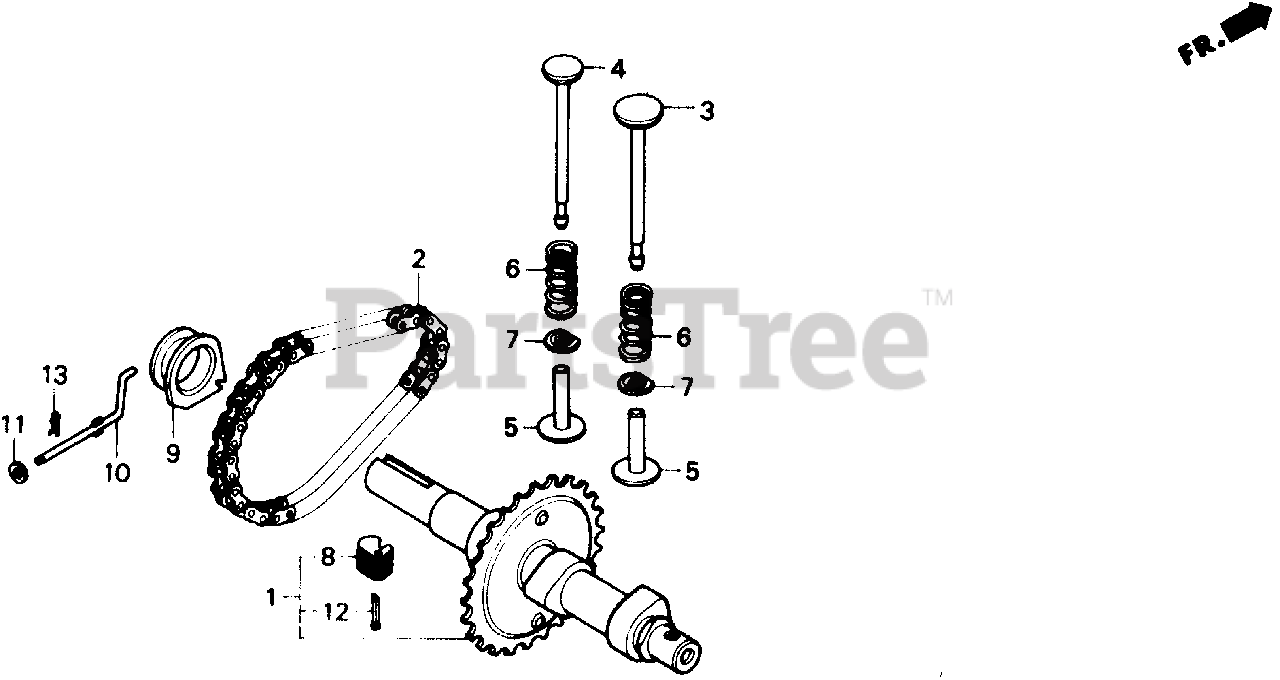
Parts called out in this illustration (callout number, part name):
1	CAMSHAFT ASSY.
2	CHAIN, CAM
3	VALVE, IN.
4	VALVE, EX.
5	LIFTER, VALVE (34.39)
5	LIFTER, VALVE (34.66)
6	SPRING, VALVE
7	RETAINER, VALVE SPRING
8	WEIGHT, GOVERNOR
9	SLIDER, GOVERNOR
10	SHAFT, GOVERNOR ARM
11	WASHER, PLAIN (5MM)
12	PIN, COTTER (3.0X45)
13	PIN, LOCK (8MM)
